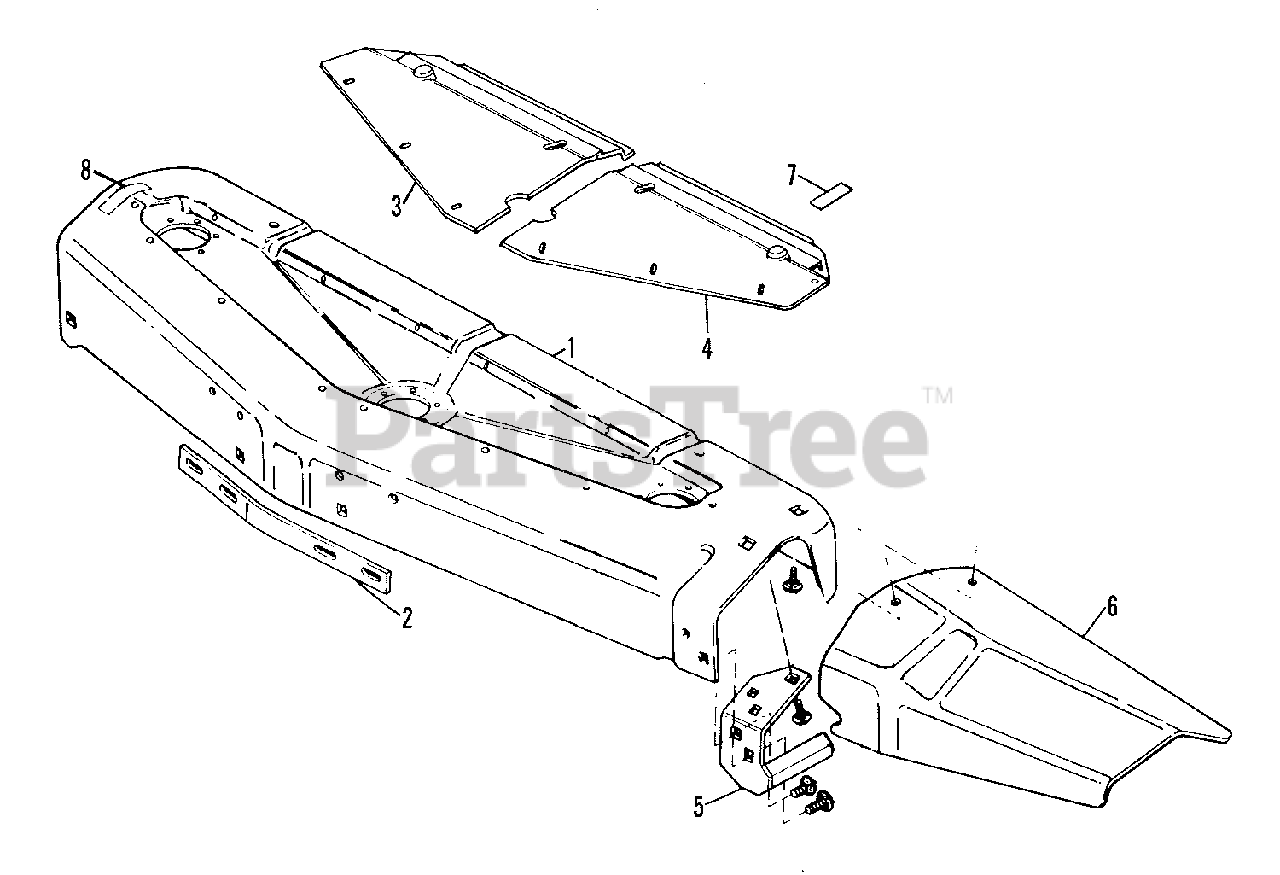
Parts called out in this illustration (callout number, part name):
1	HOUSING, 48"
2	BAR, Reinforcement
3	COVER, R.H.
3	SCREW, Taptite, 1/4NC x 3/8
4	COVER, L.H.
4	SCREW, Taptite, 1/4NC x 3/8
5	GUARD ASSEMBLY, Stone
5	BOLT, Carriage, 3/8NC x 1-1/4
5	WASHER, Plain, 13/32 x 1-1/2 x 11 Ga.
5	LOCKWASHER, 3/8
7	DECAL, Danger
8	DECAL, Danger
